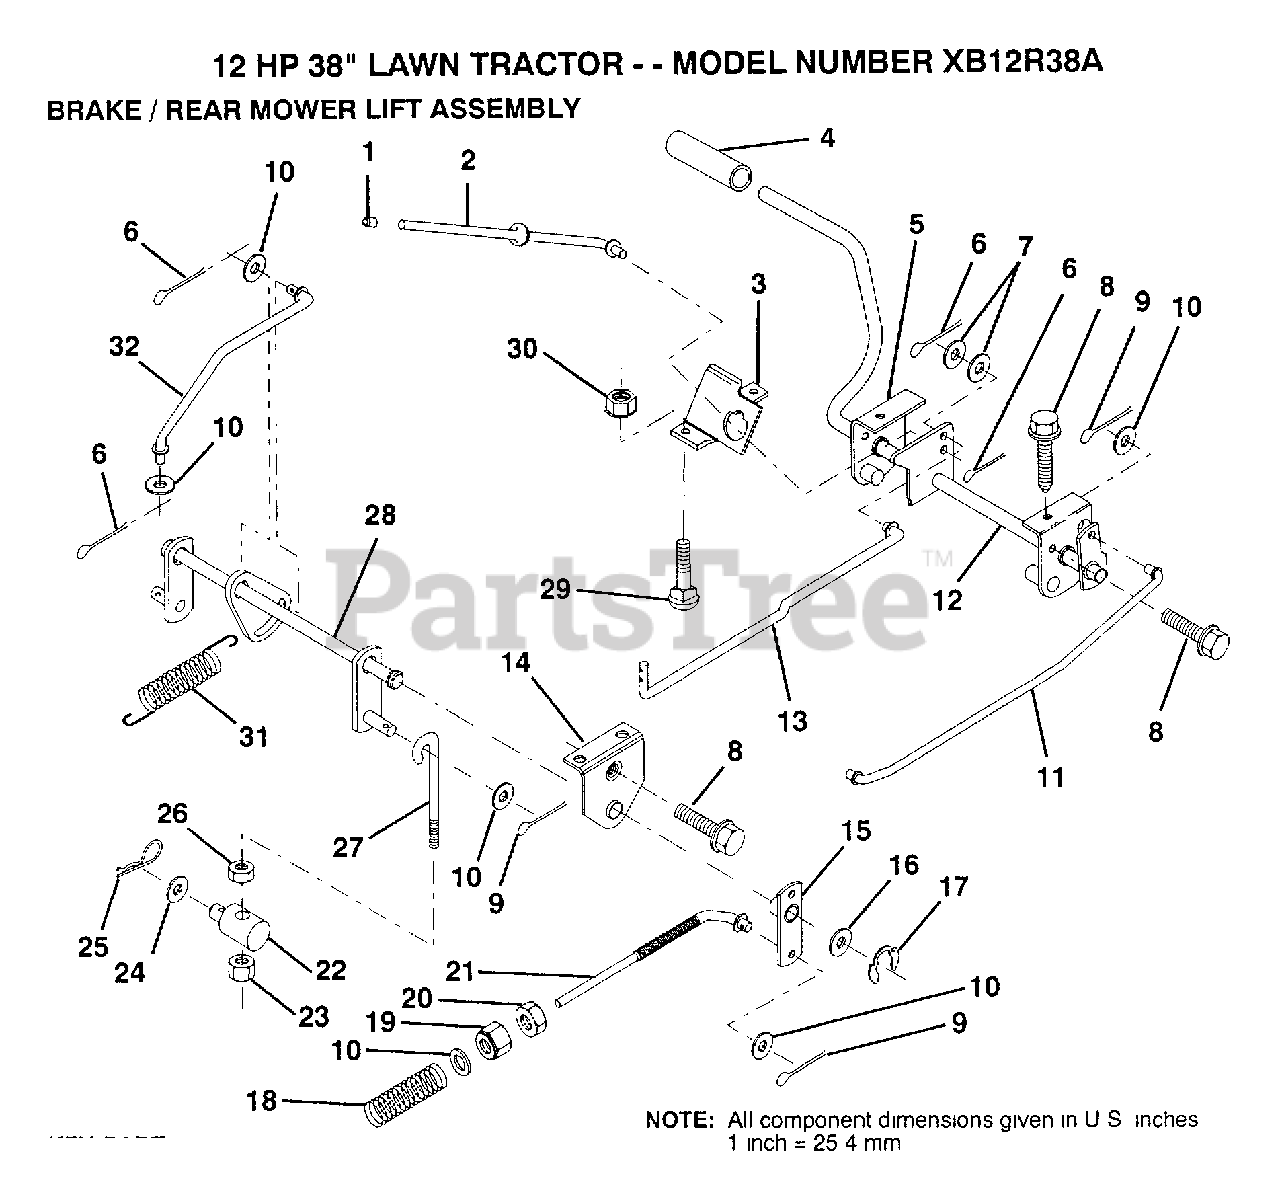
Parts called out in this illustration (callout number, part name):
1	PLUNGER CAP T
2	"ROD,PARK BRAKE"
3	"BRKT,PARK BRAKE"
4	PEDAL COVER T
5	BRK ASM CLUT LH
7	WASHER
8	SCREW LT
9	COTTER PIN
10	WASHER
11	"ROD,FRT BRAKE"
12	ASM CLUT/BRK PED
13	"ROD,CLUTCH"
14	"BRKT,LIFT SHAFT"
15	BRAKE PIVOT ARM
16	WASHER T
17	KLIP RING
18	SPRING ROD LT
19	NUT
24	WASHER
25	SPRING.RETAINER
26	LOCKNUT
27	THREADED LINK
28	ASM REAR MOW LIFT
31	COUNTER SPRING
32	LINK LIFT LEVER
